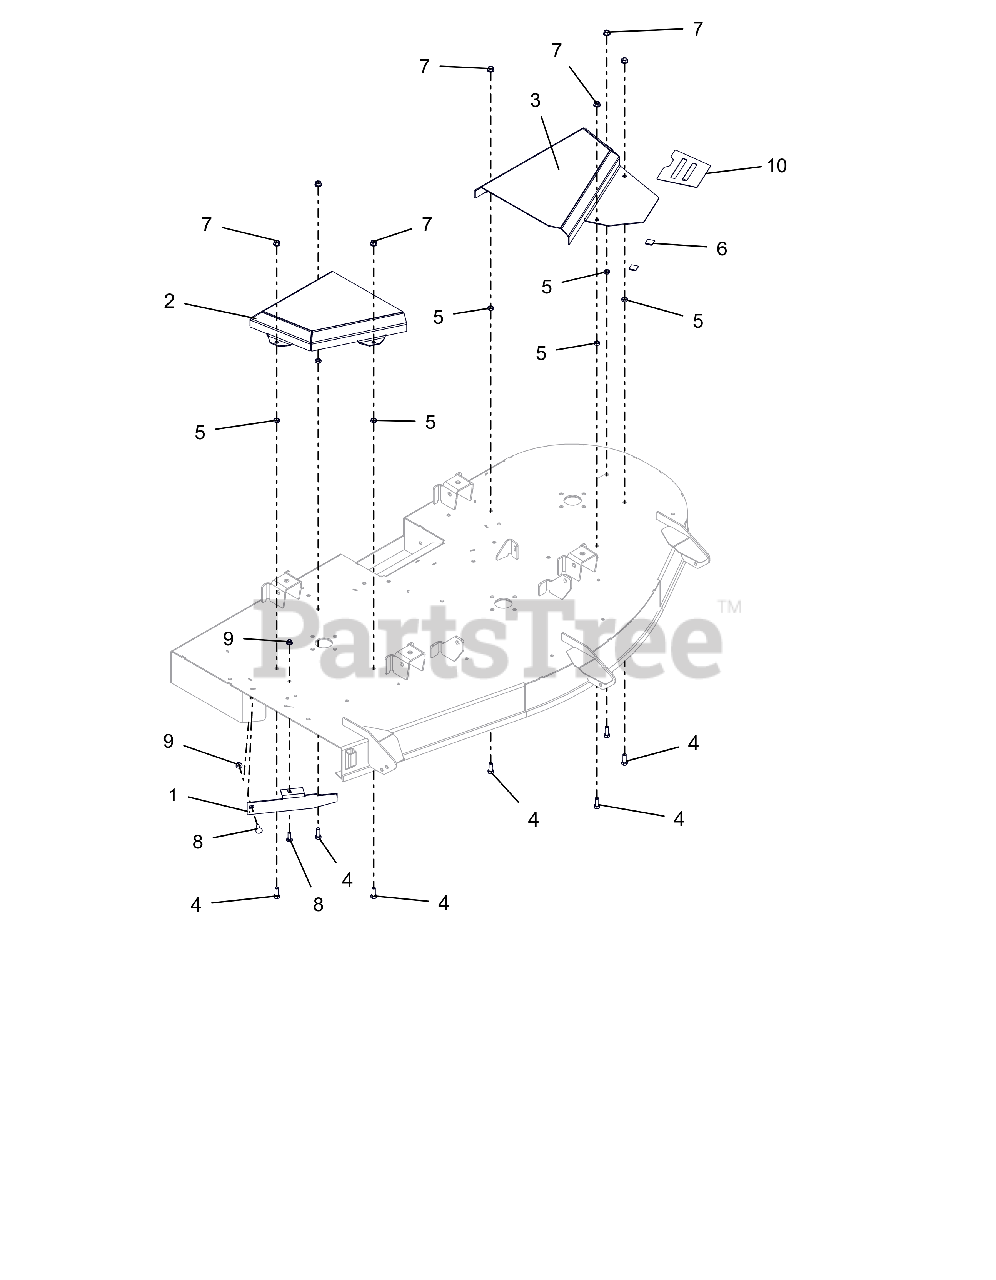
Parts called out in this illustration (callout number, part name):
1	BAFFLE, DISCHARGE 60
2	COVER, RH BELT 60
3	COVER, LH BELT 60
4	BLT,HEX .38-16X1.00 G5 ZCC
5	NUT-JAM .375-16 G2 ZCC
7	NUT-LK-TOP-FLG .38-16 ZC120
8	BLT,RHSN .31-18X1.00 G5 ZCC
9	NUT,LK-NYL-FLG .31-18 G5ZC120
10	GRIP TAPE 52-60 BELT COVER
